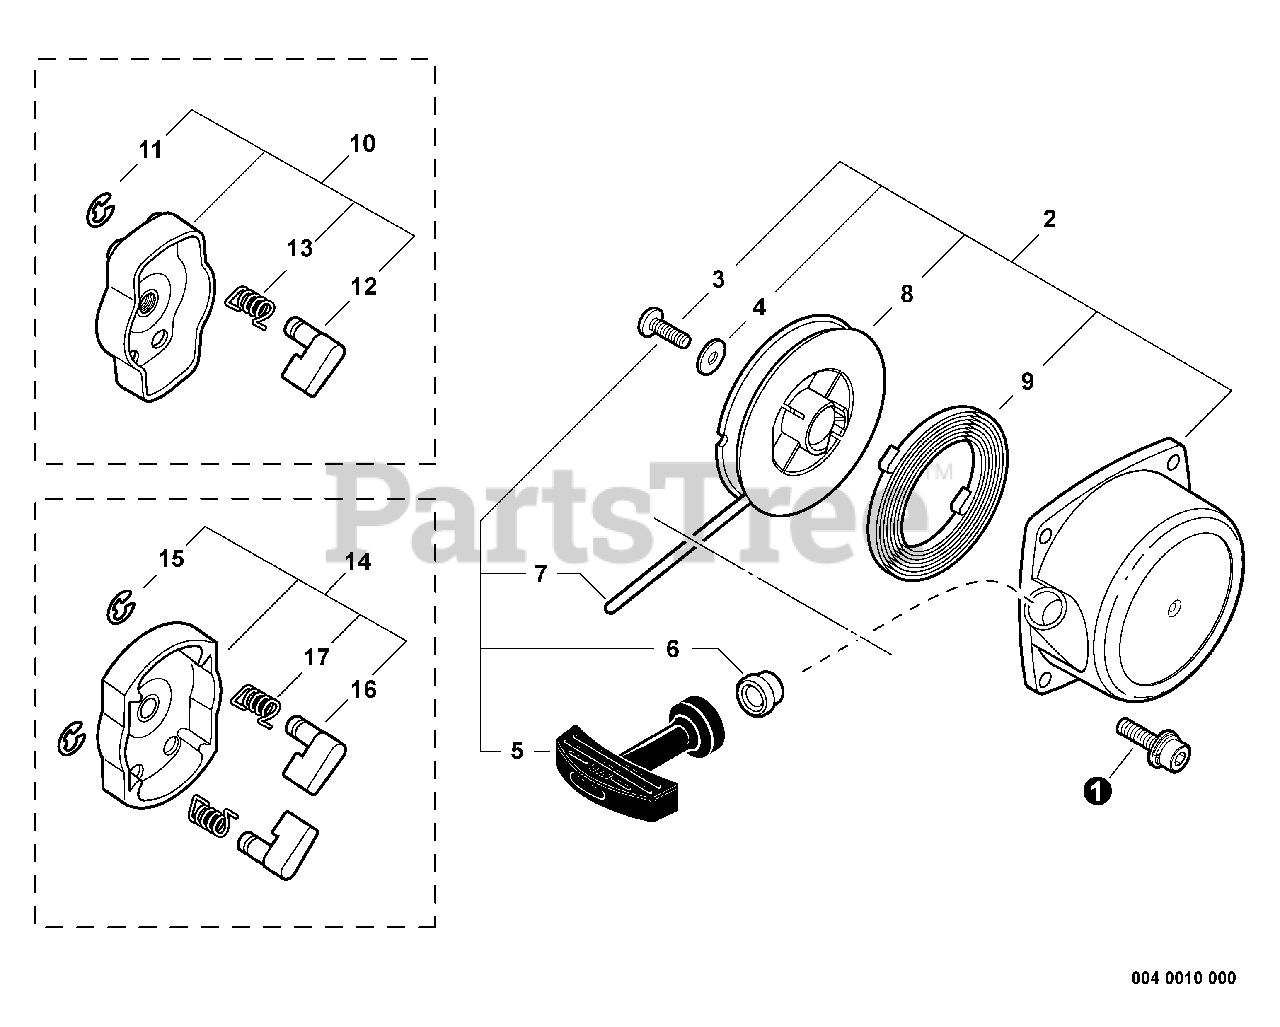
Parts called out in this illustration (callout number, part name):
1	SCREW - 4X18
2	STARTER ASSY
4	WASHER
5	GRIP, STARTER
6	GUIDE, ROPE
7	ROPE, STARTER - 4X1110
8	REEL, ROPE
9	SPRING, REWIND
10	STARTER PAWL ASSY
11	RING, RETAINING - 4
12	PAWL, STARTER
13	SPRING, RETURN
14	STARTER PAWL ASSY
15	RING, RETAINING - 4
16	PAWL, STARTER
17	SPRING, RETURN
